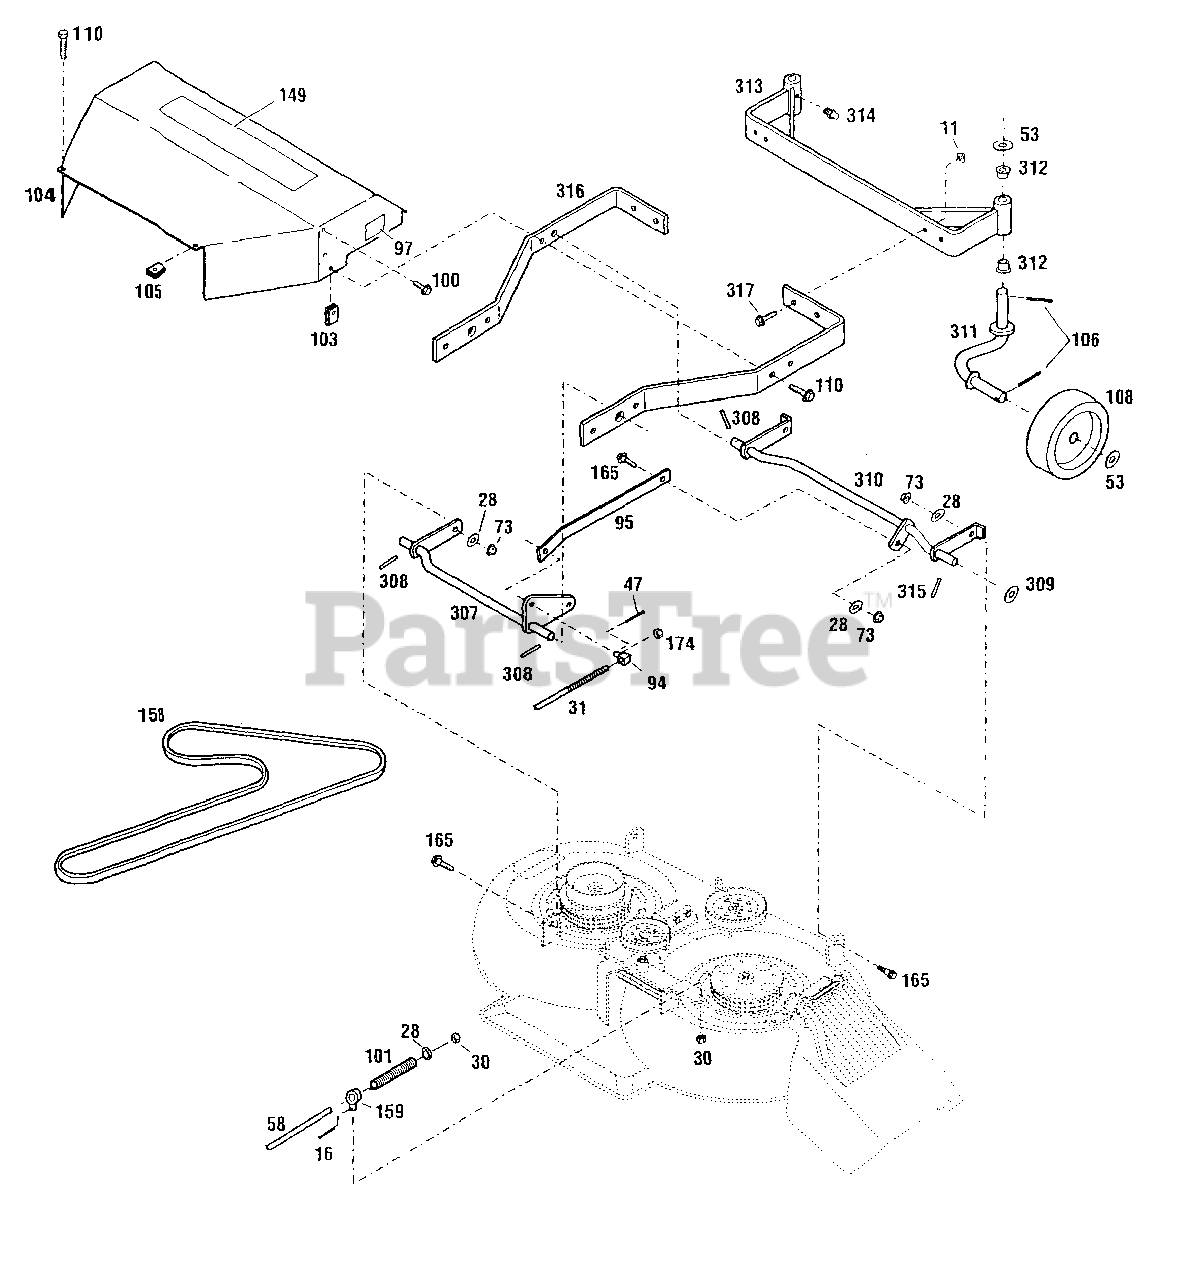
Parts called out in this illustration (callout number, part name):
11	Flange Locknut, 3/8-16
16	Cotter Pin, 3132 x 5/8
28	Flat Washer, 3/8
30	Locknut,3/8-16
31	Lift Crank
47	Cotter Pin
53	Special Washer
58	Lower Blade Rod
73	Flange Locknut, 3/8-16
94	Pivot Block
95	Leveler Bar
97	Cutting Height Decal
100	Tap Screw, #8 x 3/8
101	Compression Spring
103	Speed Nut, 5/16-18
104	Belt Guard
105	Speed Nut, 5/16-18
106	Cotter Pin
108	Gage Wheel
110	Flange Lock Screw, 5/16 x 3/4
149	Logo Decal
158	V-Belt
159	Eye Bolt
165	Shoulder Bolt
174	Toplock Nut
307	Rear Lift Assembly
308	Roll Pin, 1/4 x 1
309	Flat Washer, 5/8
310	Front Lift Assembly
311	Spindle Assembly
312	Flange Bearing
313	Gage Support
314	Grease Fitting
315	Drive Pin, 1/4 x 3
316	Mower Support
317	Whizlock Screw, 3/8-16 x 1
